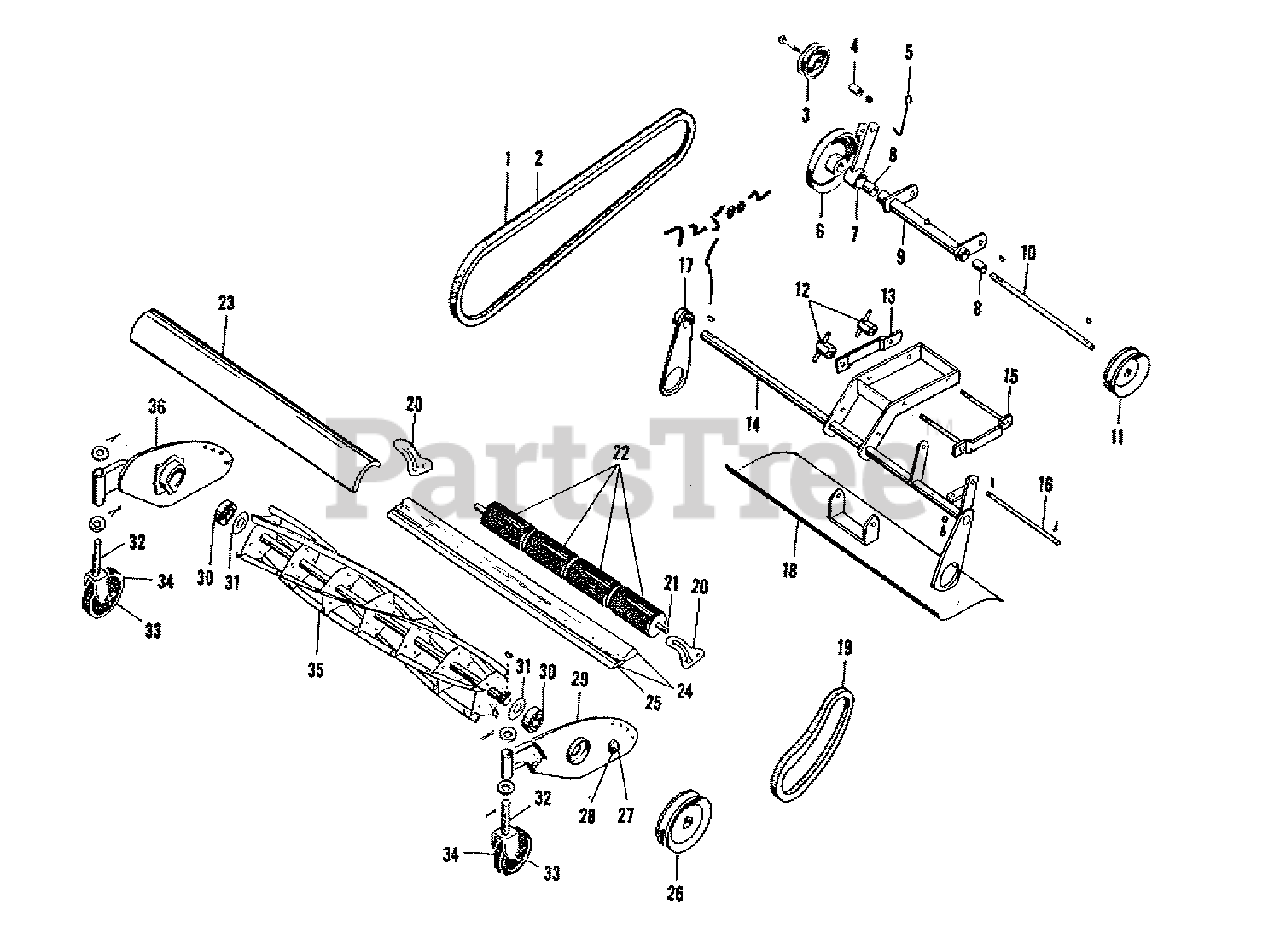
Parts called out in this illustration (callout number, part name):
1	BELT, 34" For Models LB & FB
2	BELT, 39" For Model VA
3	IDLER PULLEY
4	INNER BEARIG RACE
5	BELT STOP
6	DRIVE PULLEY
7	IDLER LEVER ASSEMBLY
8	PULLEY SHAFT BEARING'
9	BEARING HOUSING ASSEMBLY
10	PULLEY SHAFT
12	WING NUT COMPLETE
13	HITCH SIDE PLATE
14	PUSH ARM ASSEMBLY
15	HITCH CLAMP ASSEMBLY
16	BEARING HOUSING ARM SHAFT
17	PUSH BAR ASSEMBLY, R.H.
18	GRASS FENDER ASSEMBLY
20	ROLLER BRACKET
21	ROLLER SHAFT
22	ROLLER (Per Section - 4 required)
23	BRUSYH BAR
24	CUTTER BAR COMPLETE w/BLADE
25	CUTTER BAR BLADE w/RIVETS
26	SHEAVE - REEL
27	ADJUSTING CAM
28	CAPSCREW, Hex, Head 3/8-24 x 7/8
29	SIDE FRAME ASSEMBLY, L.H.
30	BALL BEARING
31	REEL BEARING WASHER
32	CASTER YOKE ASSEMBLY
33	CASTER AXLE
34	CASTER WHEEL w/BEARINGS
35	REEL ASSEMBLY L.H. w/BEARING
36	SIDE FRAME ASSEMBLY R.H.
